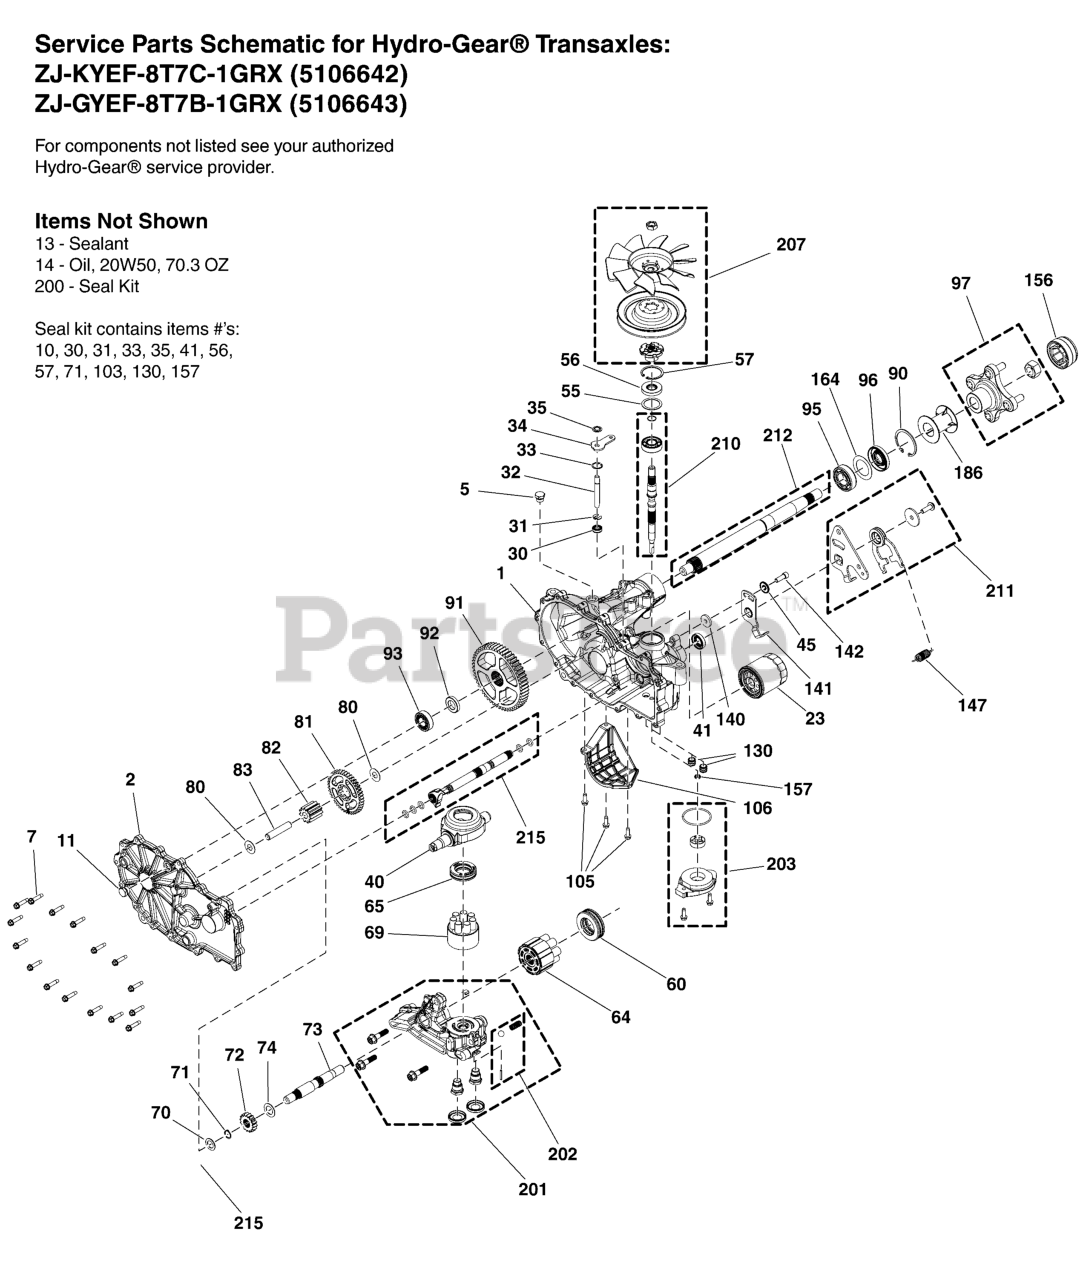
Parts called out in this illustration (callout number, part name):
1	KIT, MAIN HOUSING, LH, CHRG, CNTL
2	KIT, SIDE COVER, LH
13	TUBE, SEALANT
23	FILTER, OIL, ZT2800
30	SEAL, .375 X .750 X .25 LIP, H/G 51626
34	ARM, BYPASS
35	RING, RETAINING .375 EXTERNAL
40	SWASHPLATE, TRUNNION
41	SEAL, CONTROL ARM, 18X32X7, #51140
55	SPACER (50951)
56	SEAL, LIP, 17 X 40 X 7
57	RING, RET 2.06 INT,
64	KIT, 16cc CYLINDER BLOCK ASSEMBLY
69	KIT, BLOCK 7 PISTON
70	WASHER, .63 X 1.00 X .05 FLAT
71	RING-SNAP (44145)
72	GEAR, 16T (STEEL)
73	SHAFT, MOTOR
74	WASHER, .71 X 1.16 X .04 FLAT
80	WASHER, .51 X 1.00 X .03 FLAT
82	GEAR, 11T (STEEL)
83	PIN, JACKSHAFT
90	RING, RETAINING 2.25 INTERNAL (50859)
93	KIT, BEARING (72749)
95	BEARING BALL, 1.0 X 52 X 15 OPEN 6205M
96	KIT, SEAL, AXLE - HG# 53699
97	ASSM, HUB
106	GUARD, FILTER, LH
130	TUBE, CHARGE TRIPLE O-RING
141	ARM, NEUTRAL, LH
142	SHCS, 5/16-24 X .875 (PATCH)
147	SPRING, Extension (Used on Hydro-Gear P/N ZC-AHBB-2A7B-1DPX and ZC-AHBB-2A7B-1DPX)
156	AXLE CAP,
157	KIT, GEROTOR SEAL
164	WASHER, 1.355 x 2.035 x .021 FLAT
186	DEBRIS GUARD HG #53496
200	KIT SEAL
201	KIT, CENTER SECTION, LH CHARGE
202	KIT, CHARGE RELIEF
203	KIT, CHARGE
207	KIT, FAN/ PULLEY
210	KIT, INPUT SHAFT
211	KIT, L.H. Control Arm
212	SHAFT, AXLE
215	SEAL KIT BRAKE SHAFT ZT3400 RH 72754 NET
